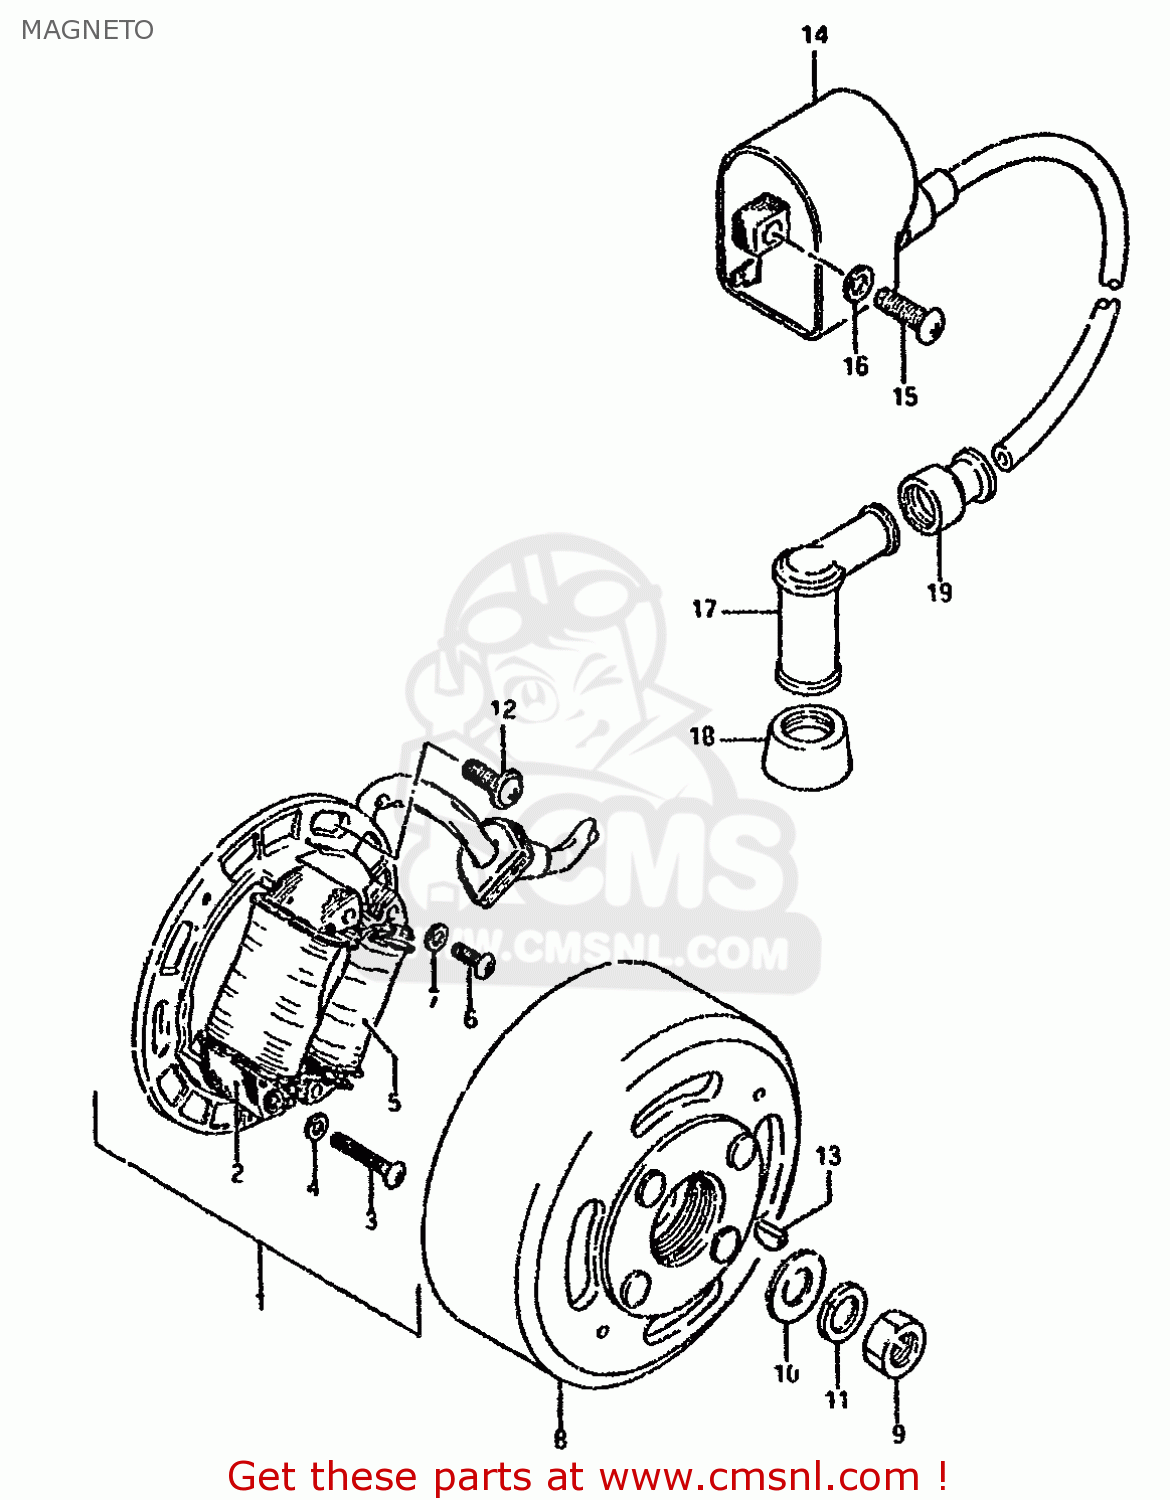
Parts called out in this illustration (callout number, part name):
1	STARTER ASSY
2	COIL,LIGHTING
3	SCREW
4	WASHER,LOCK
5	COIL,PRIMARY
6	SCREW
7	WASHER,LOCK
8	ROTOR,FLYWHEEL
9	NUT
10	WASHER
11	WASHER
12	SCREW
13	KEY
14	UNIT & COIL ASSY,IGNITION
15	SCREW
16	WASHER,LOCK
17	CAP,SPARK PLUG
18	SEAL,SPARK PLUG
19	SEAL,HIGH TENSION CORD
